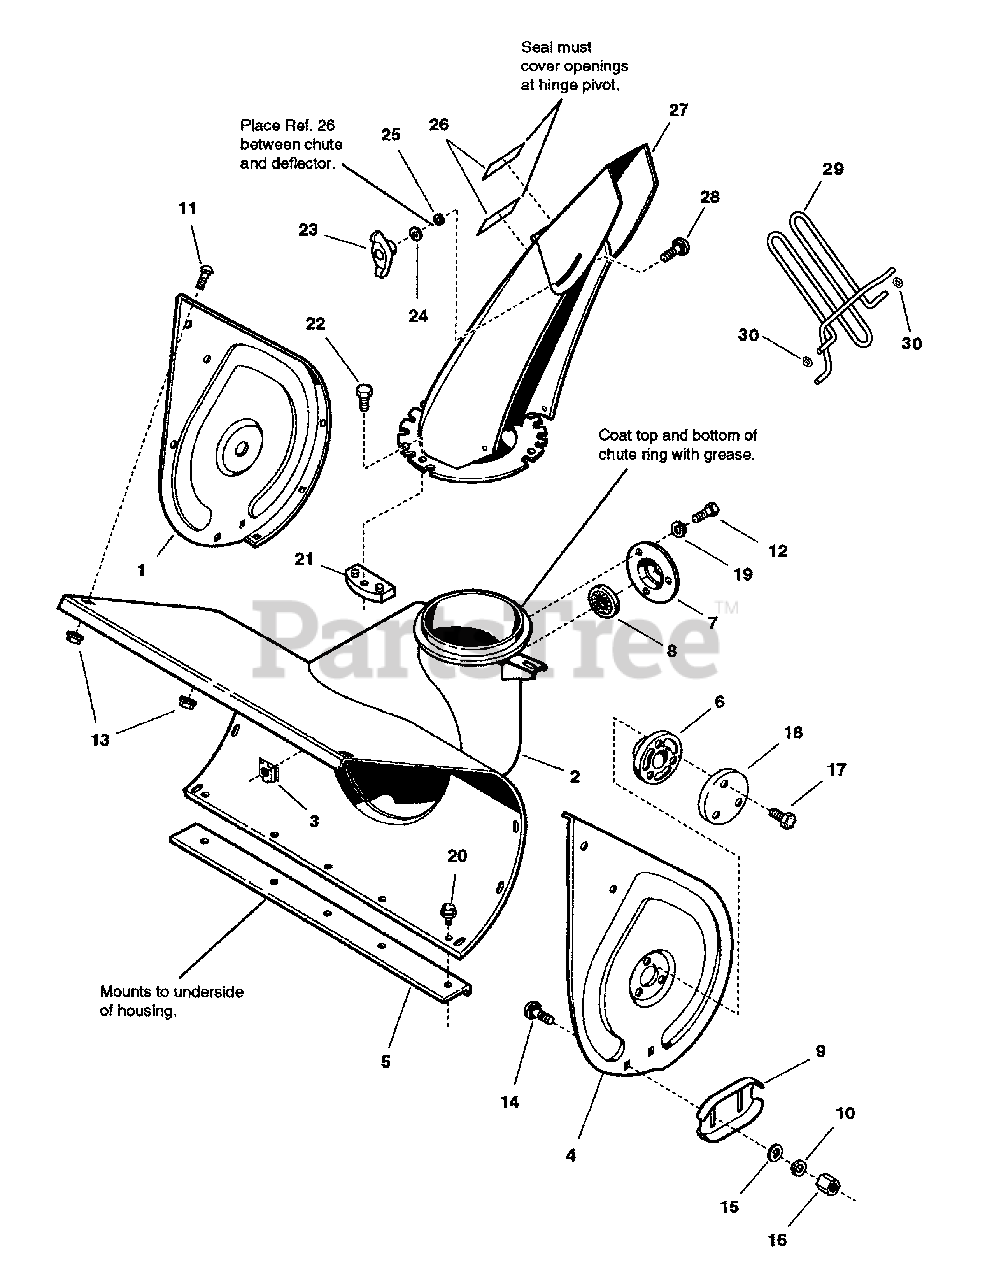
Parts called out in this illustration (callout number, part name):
1	END PLATE, RH- Auger Housing- Orange
2	WELDMENT, Auger Housing - 22" - Orange
2	WELDMENT, Auger Housing - 24" - Orange
3	RETAINER NUT, 5/16-18
4	END PLATE, LH- Auger Housing- Orange
5	BLADE, Scraper- 22"
5	BLADE, Scraper- 24"
6	BEARING, Auger
7	RETAINER, Bearing
8	BALL BEARING
9	SKID SHOE, Reversible- Orange
10	WASHER, 3/8" Split Lock
11	BOLT, 1/4-20 x 1/2" Short Square Neck Carriage, GR 5
12	SCREW, 5/16-18 x 5/8" Hex Head Cap, GR 5
13	NUT, 1/4-20 Hex Flange Lock Large
14	BOLT, 3/8-16 x 3/4" Square Neck Carriage
15	WASHER, 3/8" Flat
16	NUT, 3/8-16 Hex Nyloc
17	SCREW, 5/16-18 x 1" Hex Washer Self-Tap
18	CAP, Bearing, Orange
19	WASHER, 5/16" Split Lock
20	SCREW, 1/4-20 x 3/8" Hex Washer Self-Tap
21	RETAINER, Spout
22	SCREW, #10-24 x 5/8" Hex Washer Self-Tap
23	WING KNOB, 5/16-18 (Black)
24	WASHER, .34 x .69 x .08 Flat
25	WASHER, .388 I.D. x 1.12 O.D. x .03
26	DECAL, Hinge, Orange
27	CHUTE, Discharge
28	BOLT, 5/16-18 x 3/4" Short Square Neck Carriage, GR 5
29	WELDMENT, Chute Guard, Simplicity
30	PUSHNUT, 1/4"
